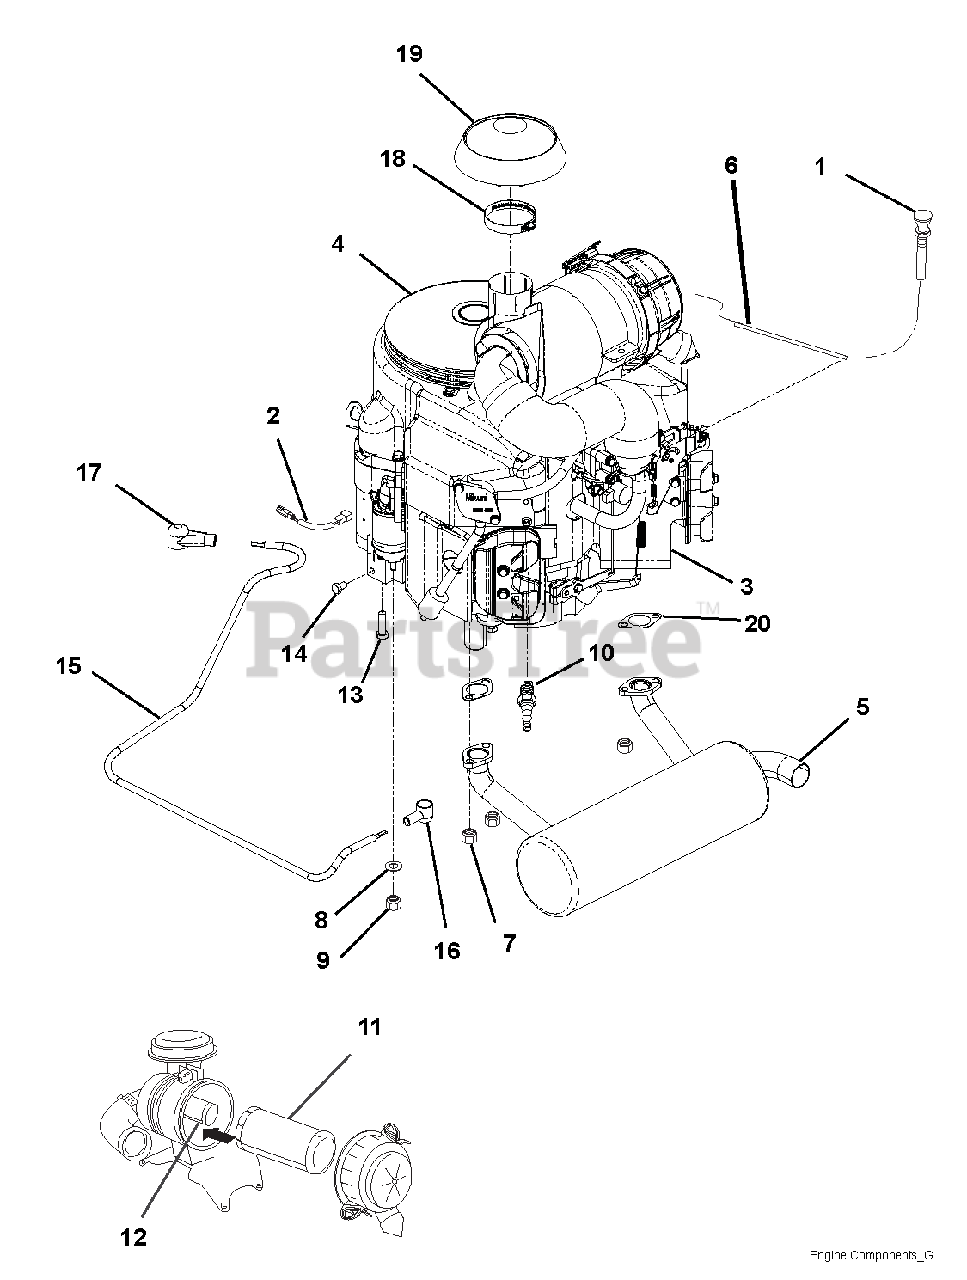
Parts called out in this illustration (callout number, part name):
1	CABLE, CHOKE 48.0"
2	LEAD - STARTER SOLENOID
3	FILTER,OIL - KAW
4	ENGINE, KAWASAKI FX751 (27HP)
5	MUFFLER - 31HP KAWASAKI VERT.
6	WIRE HARNESS
7	NUT, EXHAUST MAN. SUBARU EH
8	WSHR-LK M8 YWZC
9	NUT, M8X1.25 HEX GR8.8 Y
10	PLUG, SPARK
11	ELEMENT-OUTER - KAWASAKI
12	ELEMENT-INNER - KAWASAKI
13	BLT-HEX.38-16X1.25FTHG5 EP30YZ
14	BOLT, M8X1.25X14 HEX 8.8 Y
15	CABLE, BATTERY - 42" POSITIVE
16	BOOT, EYELET TERMINAL
17	BOOT, BATTERY TERMINAL-RED
18	CLAMP, HOSE 2.75 DIA WORM
19	RAIN CAP, AIR CLEANER (2.5")
20	GASKET, MUFFLER S/O
